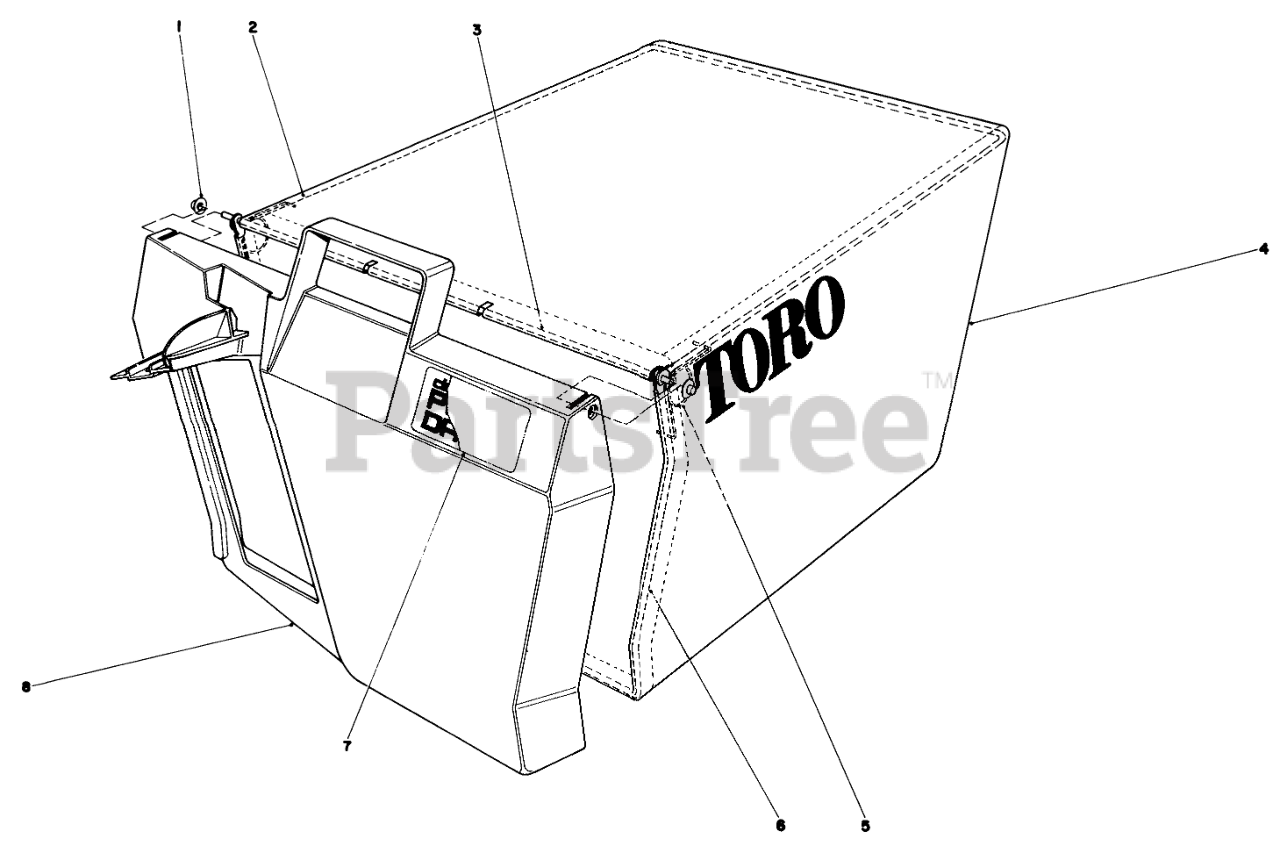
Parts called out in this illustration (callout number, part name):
1	NUT-PUSH
2	Bag Frame Upper
3	HINGE-DOOR, BAG
4	Bag
5	SPRING
6	Frame Bag
7	Decal Bag Door
8	Door Grass Bag
